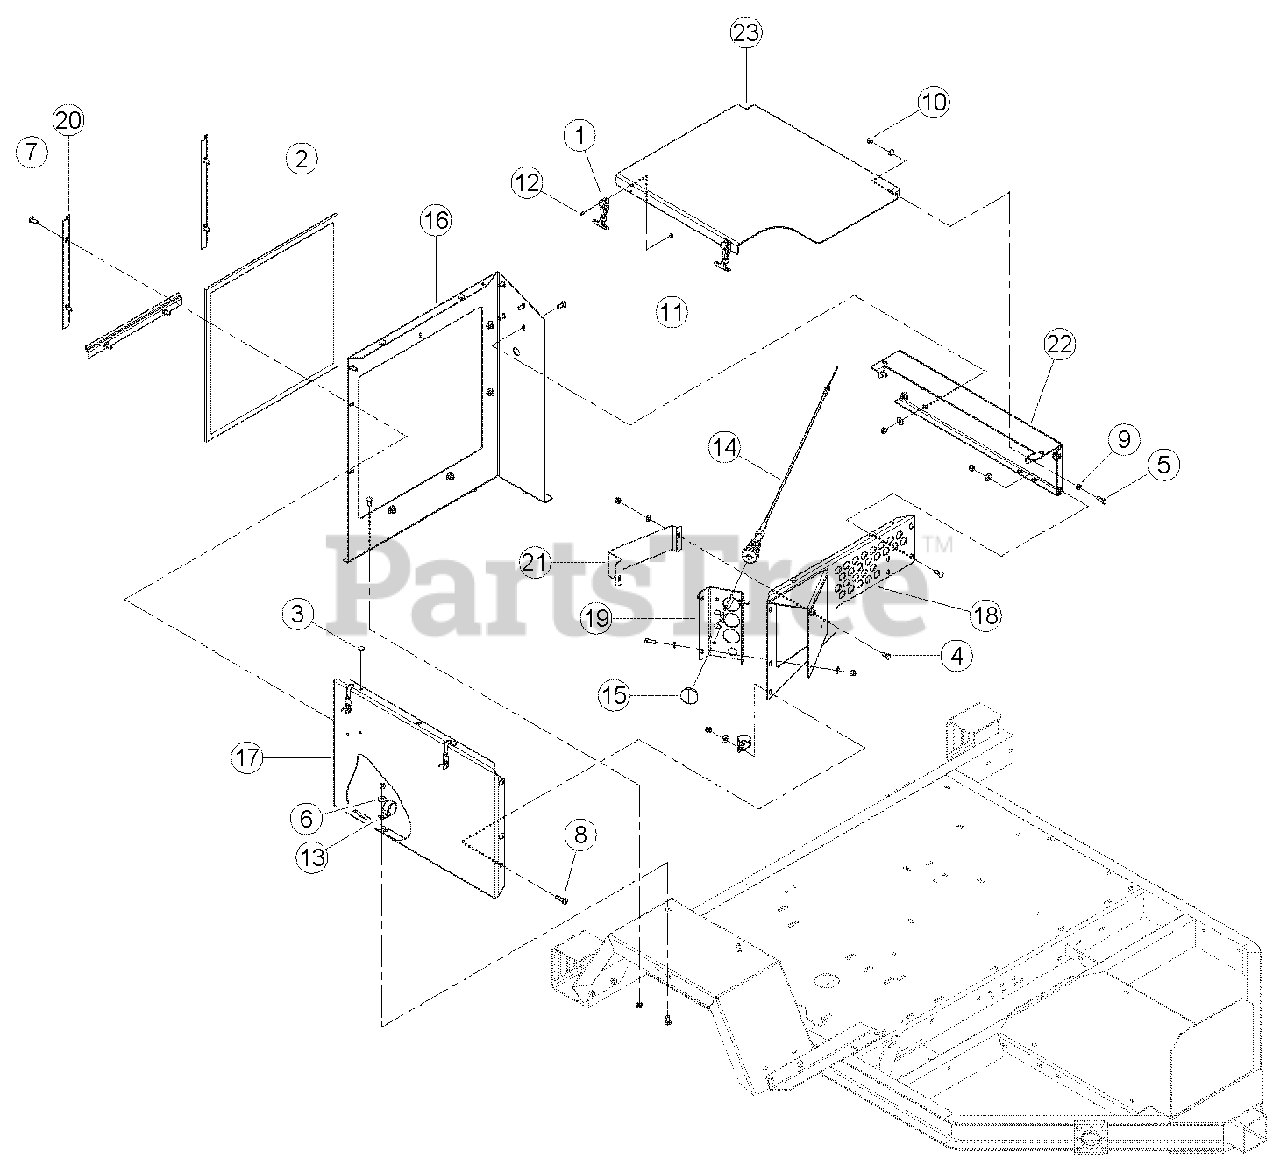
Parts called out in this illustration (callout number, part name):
1	LATCH, FLEXIBLE DRAW
2	SCREEN, RADIATOR INLET
3	BUMPER, RUBBER
4	BOLT, 3/8 X 3/4 HEX HD GR5 ZP
5	BOLT, 3/8 X 1 HEX HD GR5 ZP
6	WASHER, 3/8 FLAT ZP
7	BOLT, 3/8 X 1 CRG GR5 ZP
8	BOLT, 3/8 X 1-1/2 CRG GR5 ZP
9	WASHER, 3/8 SAE FLAT ZP
10	NUT, 3/8 NE NYLOCK ZP
11	NUT, 10/24 NYLOCK TYPE NM ZP
12	SCREW, MCH 10-24 X 1/2 PAN HD PH ZP
13	CLAMP, 1-9/16 COATED METAL
14	CABLE, DIESEL THROTTLE
15	PLUG, 2 IN. DOME
16	COVER, RADIATOR
17	COVER, ENGINE SIDE
18	WELDMENT, REAR ENGINE COVER
19	PANEL, KUBOTA ENGINE CONTROL
20	BRACKET, SCREEN HOLDER
21	SHIELD, 28 HP HEAT
22	SIDE, ENGINE COVER
23	HOOD, ENGINE
